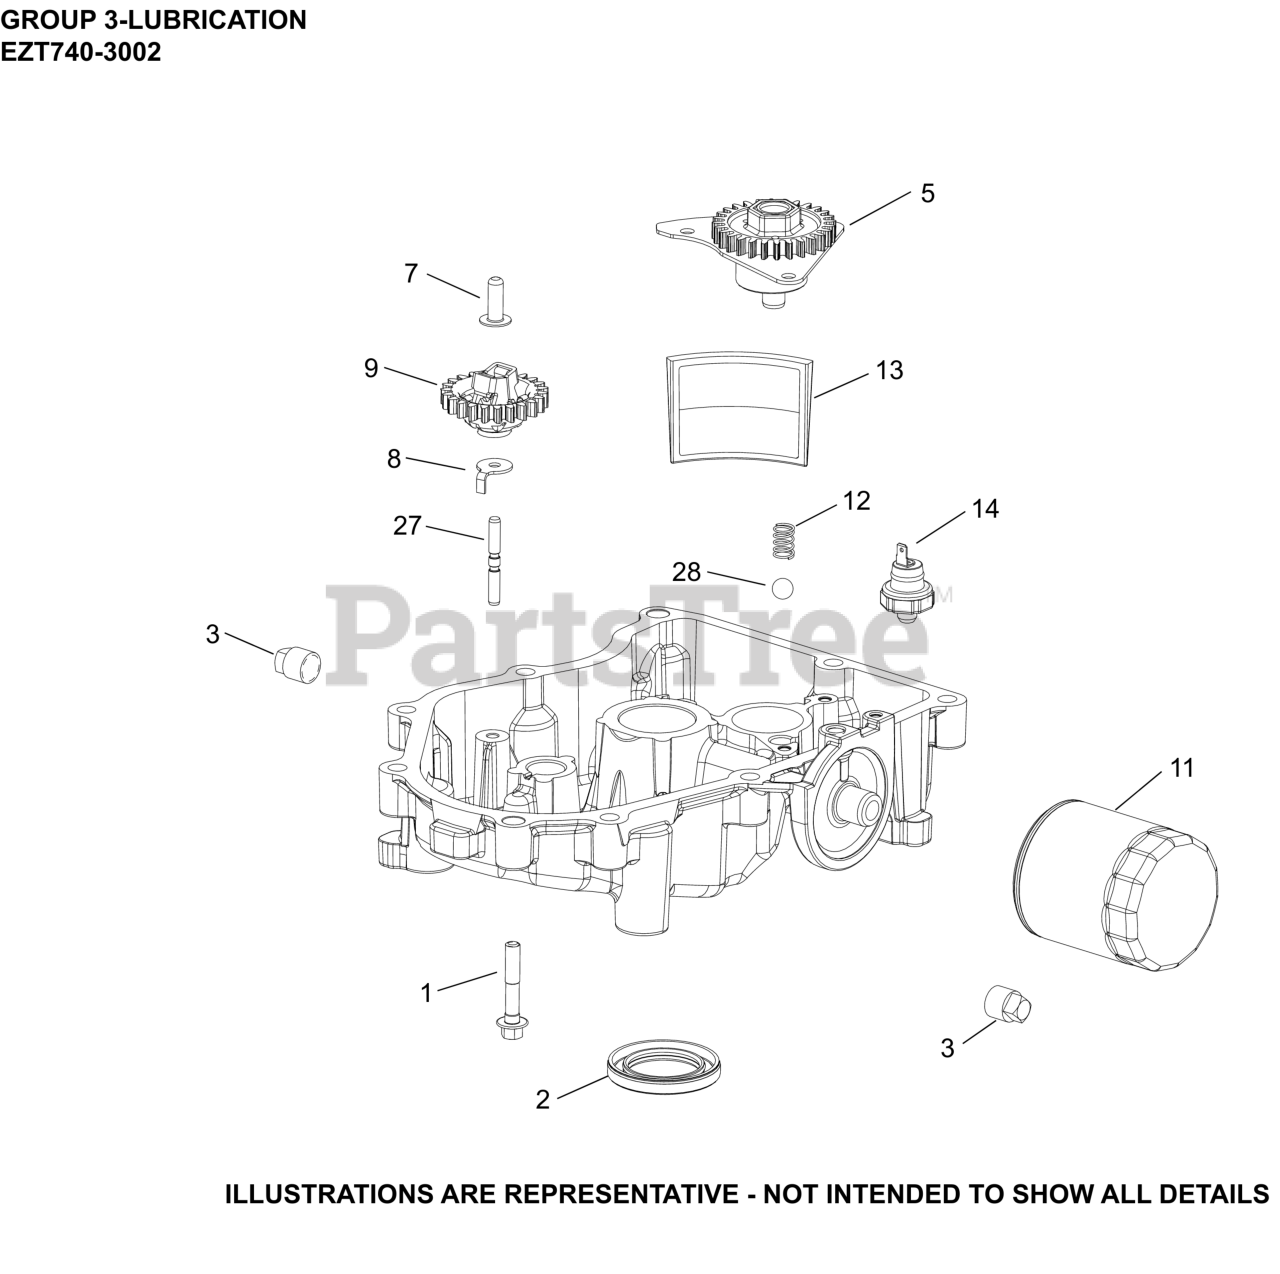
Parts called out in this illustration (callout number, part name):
1	SCREW, FLG M8X1.25X45
3	PLUG, SQ HD PIPE 3/8"
5	PUMP ASSEMBLY, OIL
7	PIN, GOVERNOR REGULATING
8	TAB, LOCKING
9	KIT, GOVERNOR GEAR
11	OIL FILTER
12	SPRING, COMPRESSION
13	SCREEN, OIL
14	SENSOR, OIL PSI
27	SHAFT, GOVERNOR GEAR
28	PRESSURE RELIEF BALL
NI	SCREW, BUTTON HEAD
